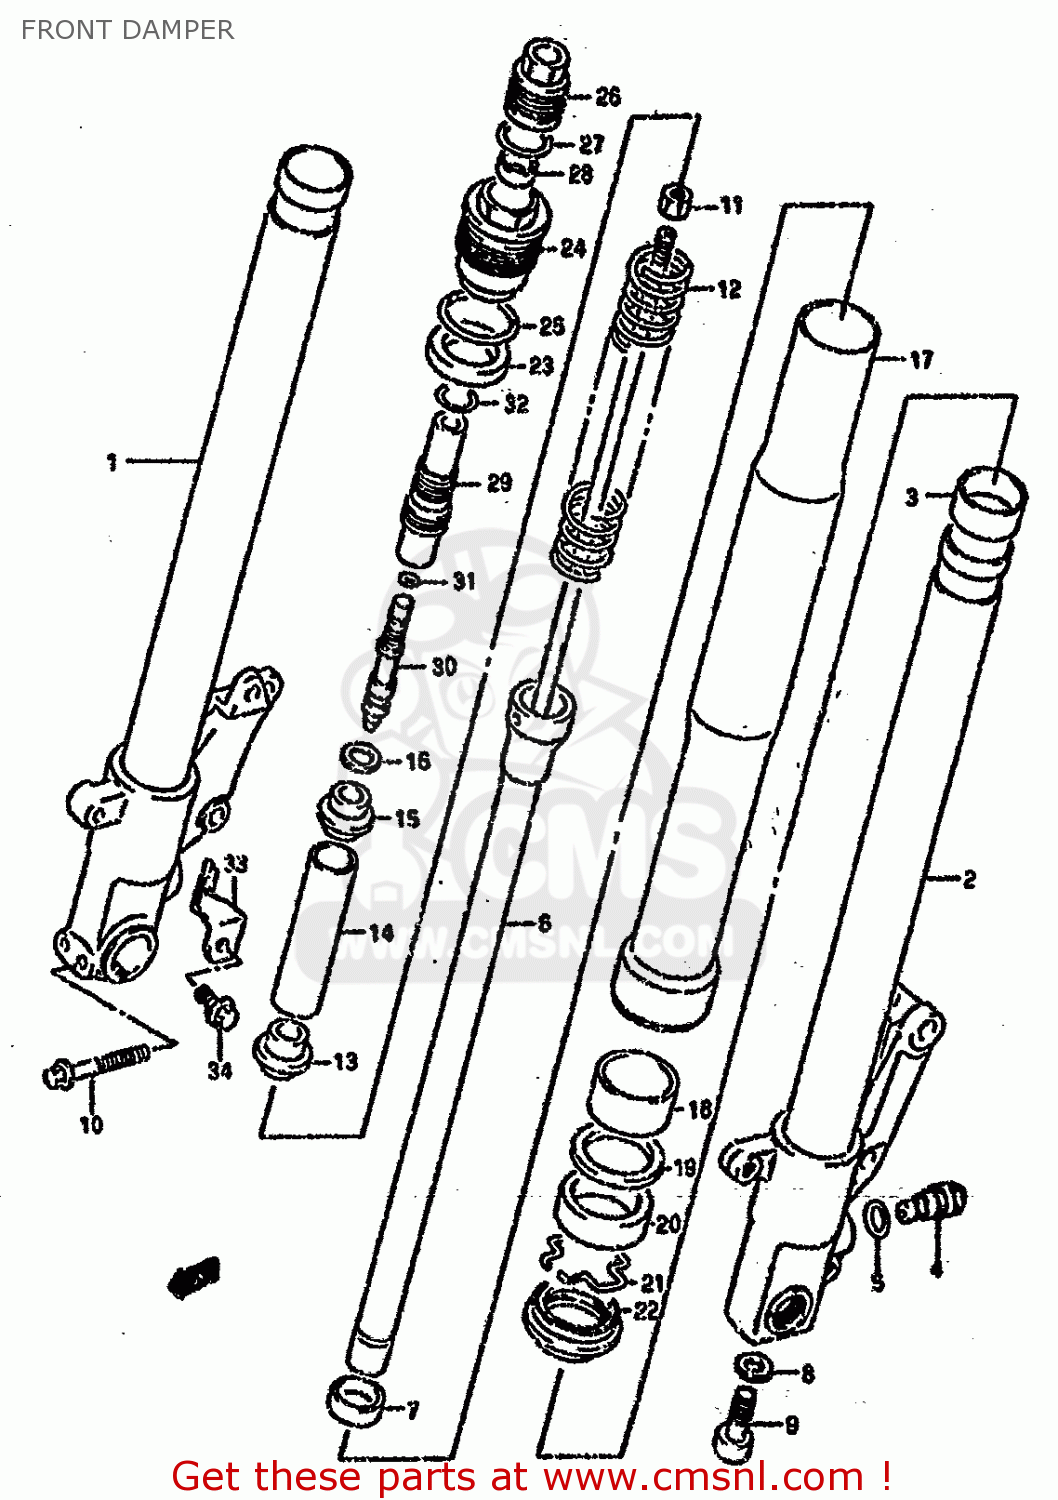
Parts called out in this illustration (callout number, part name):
1	TUBE,INNER,R
2	TUBE,INNER,L
3	BUSH,SLIDE
4	PIECE,ADJUSTER
5	O-RING (D:2.4 ID:13.8)
6	DAMPER,FRONT
7	PLATE,CENTERING
8	WASHER(10X15X1.5)
9	BOLT
10	BOLT
11	NUT
12	SPRING,MAIN
13	JOINT,SPRING
14	SPACER,SPRING
15	GUIDE,SPRING UPR
16	GUIDE,SPRING
17	TUBE,OUTER
18	BUSH,GUIDE
19	SPACER,SEAL
20	SEAL,OIL
21	CIRCLIP,FORK OIL SEAL
22	SEAL,DUST
23	RUBBER,SEAT
24	BOLT,FORK
25	O RING,FORK BOLT
26	ADJUSTER,SPRING
27	O RING
28	PLATE,SPRING ADJUSTER
29	CASE,ADJUSTER
30	PIECE,ADJUSTER
31	O RING(D:1.9,ID:3.8)
32	RING,STOPPER
33	PLATE,FRONT FENDER,LEFT
34	BOLT
